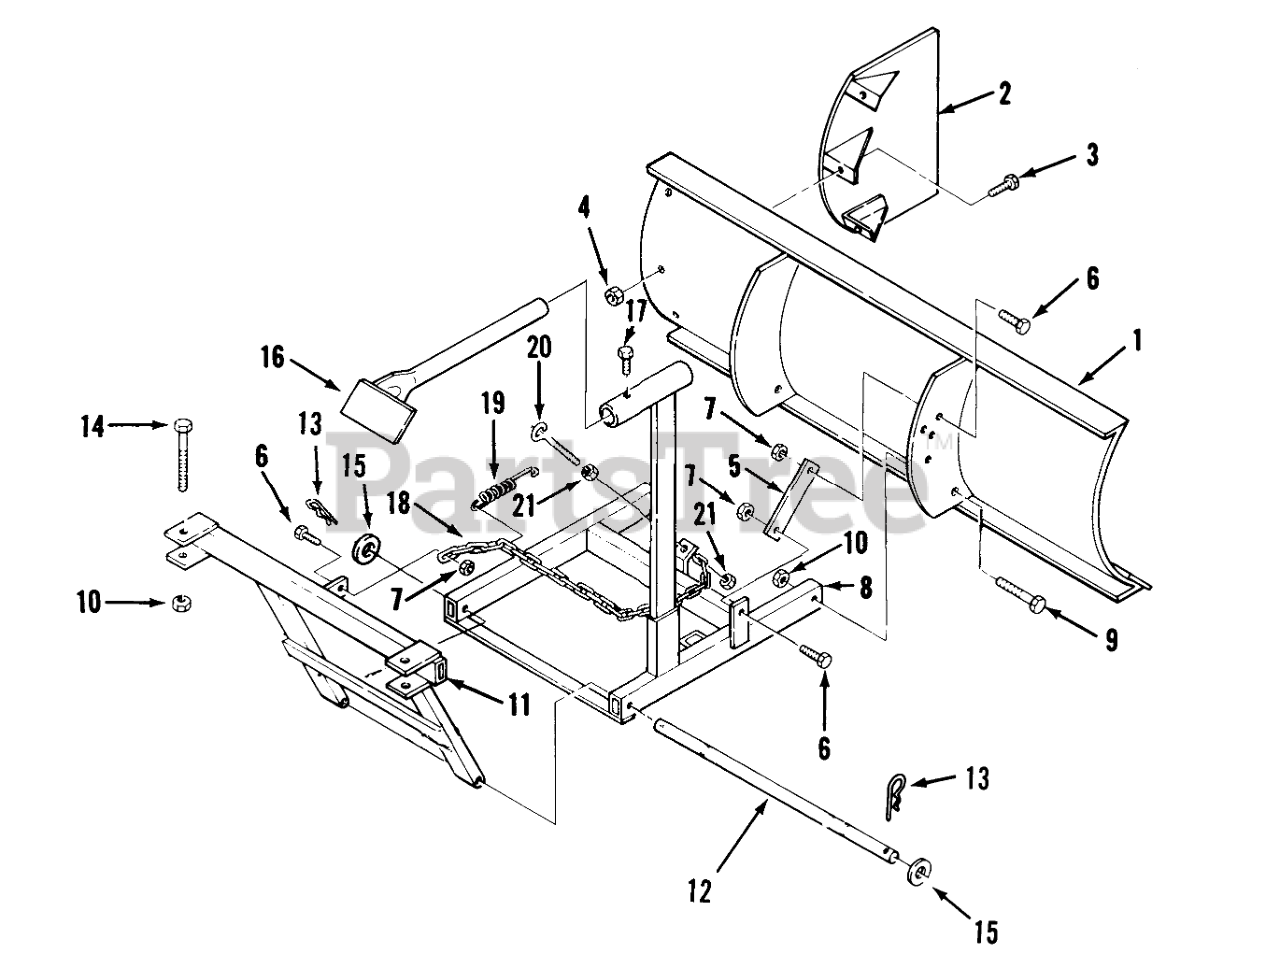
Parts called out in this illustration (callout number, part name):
1	Blade
2	End Plate
3	BOLT SCREW 10-32X1
4	Nut
5	ADJUSTING STRAP
6	Bolt
7	Nut
8	Front Frame
9	Bolt 1/2-13 X 2
10	Eslok Nut
11	ASS'Y-SNOW BLADE MTG
13	Hairpin Cotter
14	HEX HD CAP SCREW
15	Washer
16	PEDAL
17	Set Screw
18	CHAIN
19	Spring
20	Eye Bolt
21	Flanged Nut
